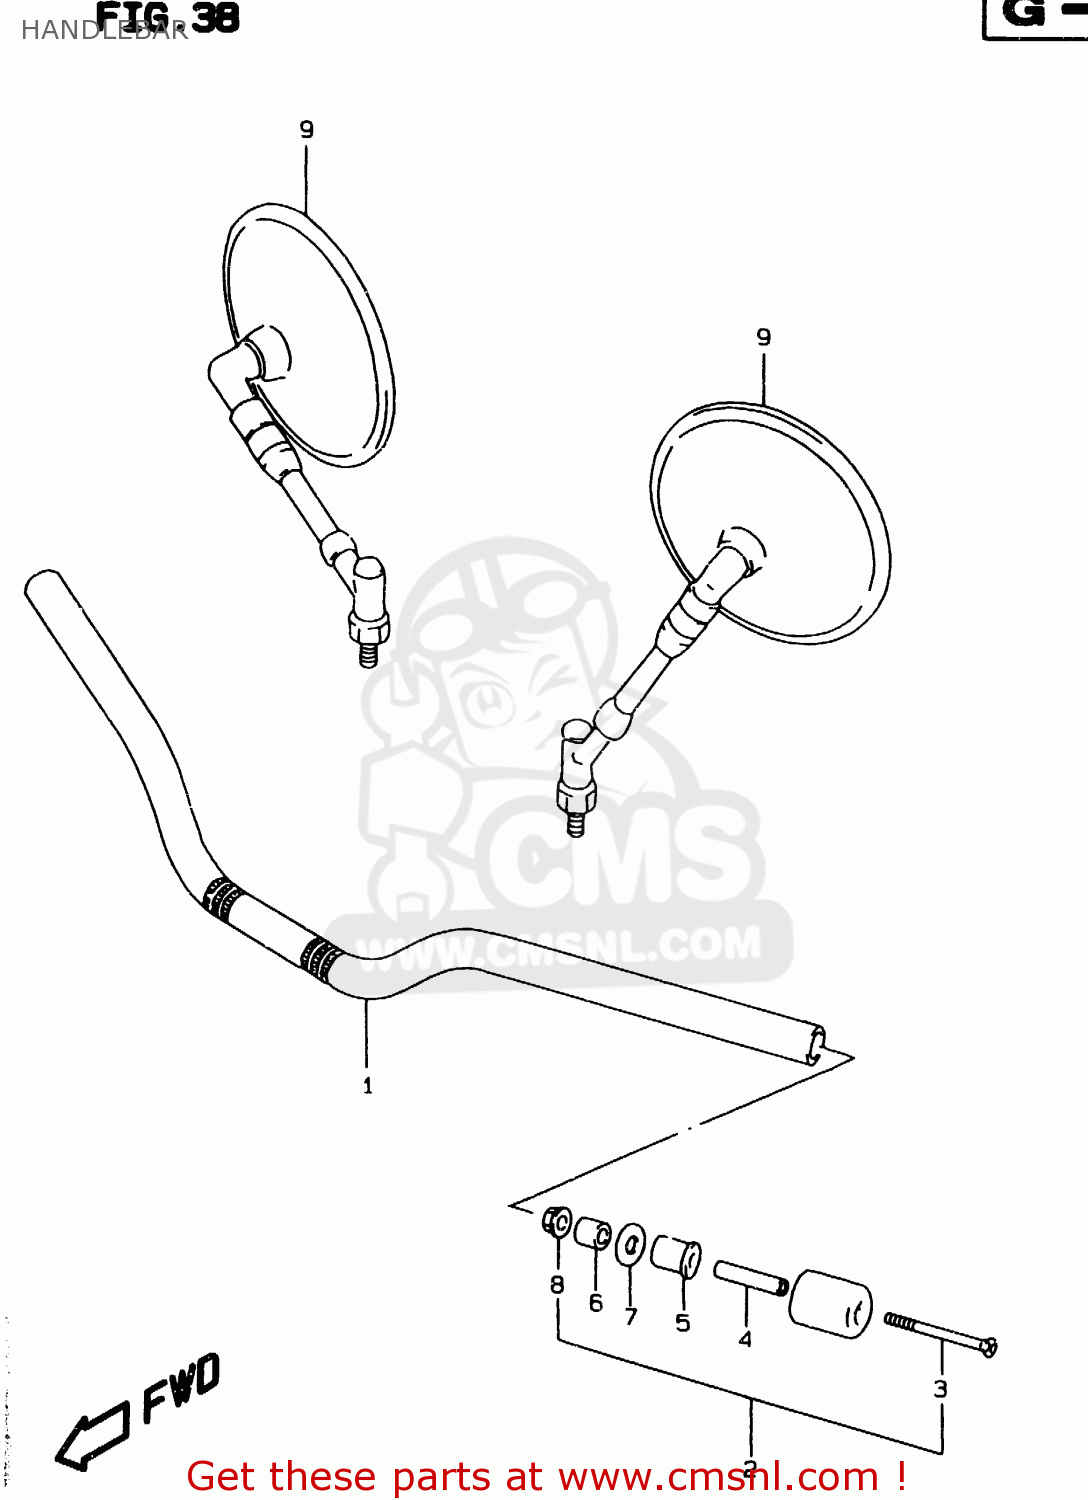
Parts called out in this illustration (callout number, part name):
1	HANDLEBAR
2	BALANCER SET,HANDLEBAR
3	SCREW(6X125)
4	SPACER,EXPANDER
5	EXPANDER,HANDLE BALANCER
6	EXPANDER,HANDLE
7	WASHER
8	NUT
9	MIRROR ASSY,RH
